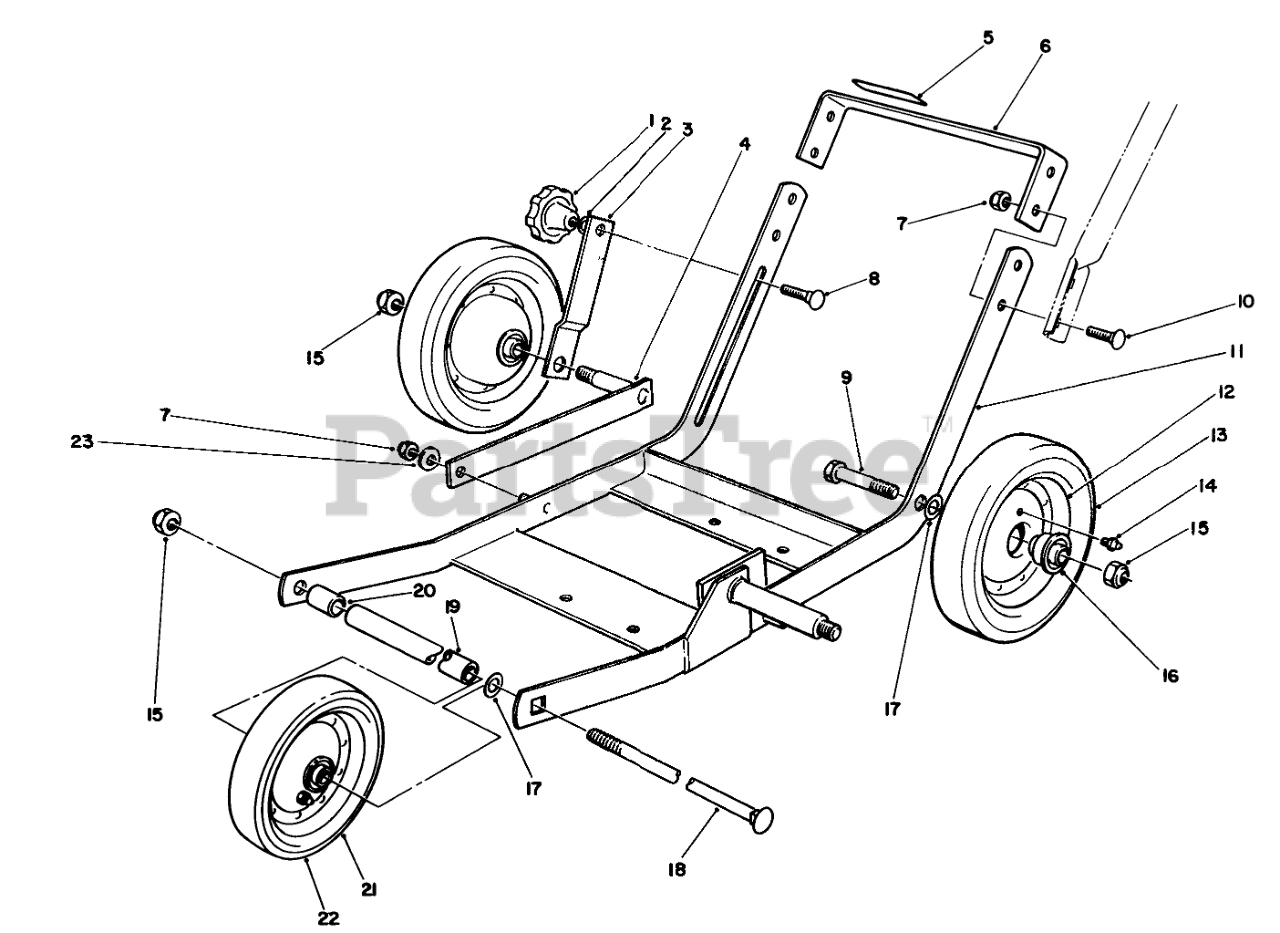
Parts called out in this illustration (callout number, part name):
2	BELLEVILLE SPRING WASHE
3	WHEEL LINK R
4	BAR WA RO
5	Decal-Warning
6	Bar-Escutcheon
7	NUT-LOCK, NI
8	SCREW-CARR
9	SCREW-HH
10	SCREW-CARR
11	Frame Assembly
12	Wheel & Tire Assembly-8" (Incl. Ref. #13, 14 & 16)
14	FITTING-GREASE
15	NUT-LOCK, NI
16	FLANGED BEARING
17	WASHER-PLAIN
18	CARRIAGE BOLT
19	AXLE SPACER
20	SPACER
21	Wheel & Tire Assembly-7"(Incl. Ref. #14, 16 & 22)
22	TIRE 7"
23	WASHER-FLAT
